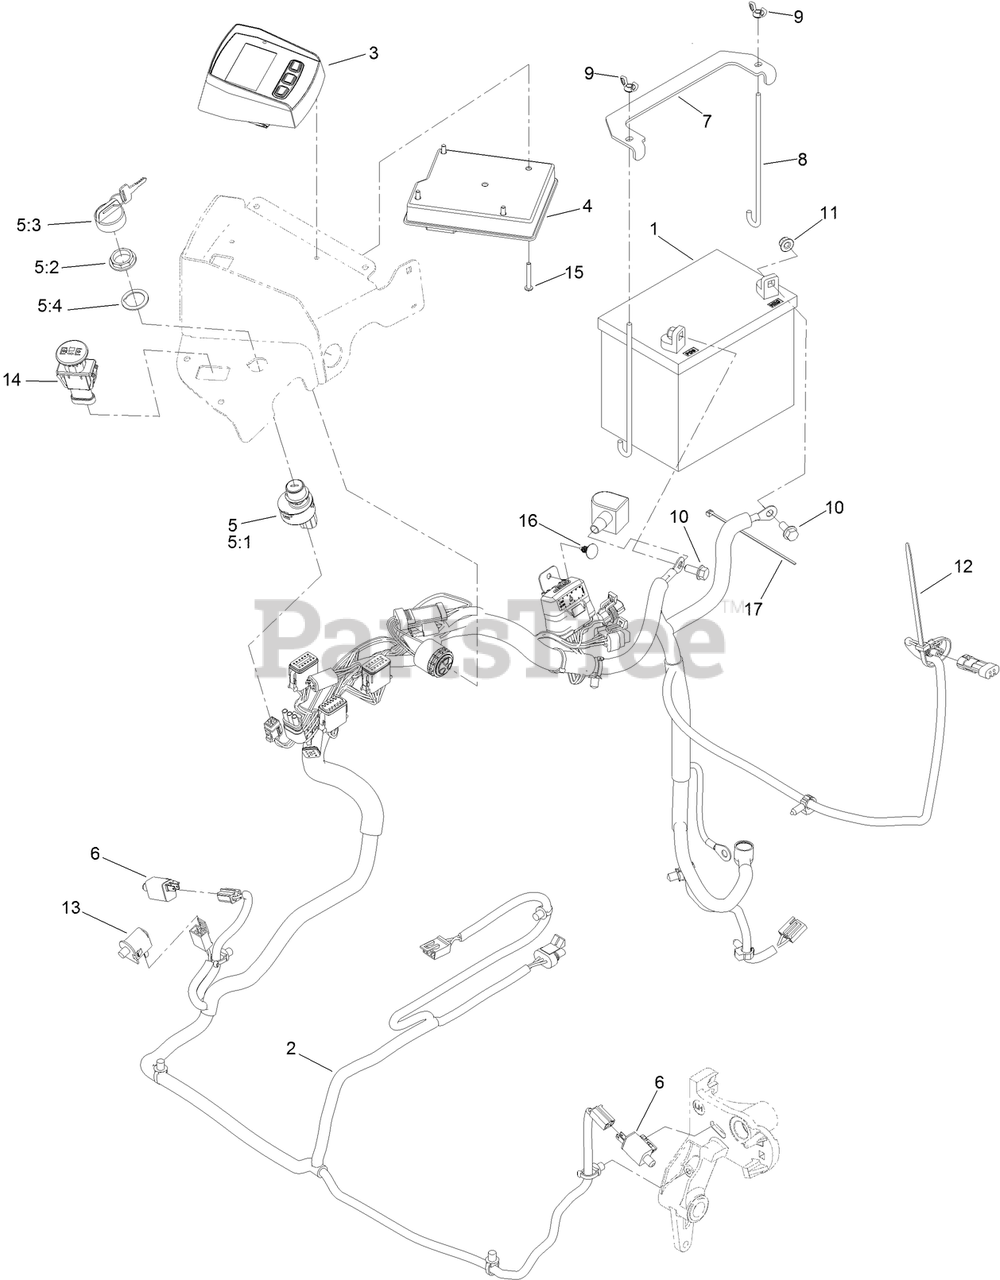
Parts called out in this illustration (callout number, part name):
1	BATTERY-DRY
2	HARNESS-WIRING
3	MODULE-HORIZON
4	MODULE
5	IGNITION SWITCH ASM
5:1	HUB and BEARING ASM
5:2	NUT-MOUNTING
5:3	IGNITION KEY SET
5:4	WASHER-BACKUP
6	SWITCH
7	STRAP-TIE DOWN, BATTERY
8	BOLT-HOLDDOWN
9	WINGNUT
10	SCREW-HHF
11	NUT-HF, NI
12	TIE-PLASTIC
13	SWITCH-BAIL
14	SWITCH-PTO, SEALED
15	SCREW-PPH
16	PLUG-PLASTIC
17	TIE-CABLE
